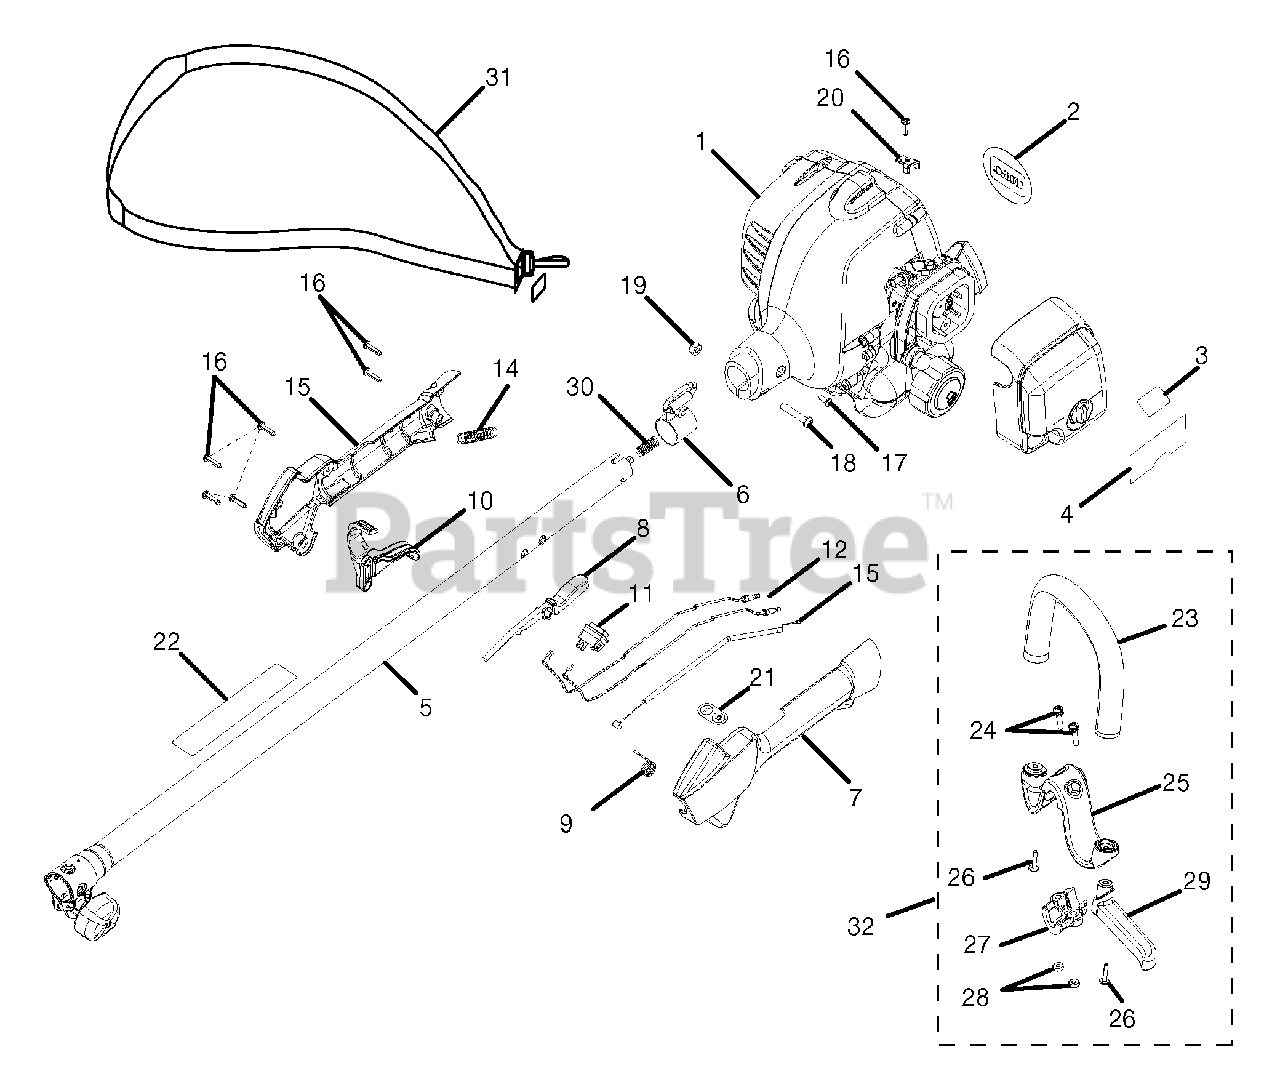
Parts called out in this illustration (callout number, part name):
1	Engine Assembly
2	Logo Label
3	Upper Start Label
4	Lower Start Label
5	Upper Shaft Assembly
6	Hanger Bracket
7	Rear Handle Support
8	Lock-off Button
9	Trigger Spring
11	Switch with Dust Shield
13	Cable, throttle
14	Corrugated Tube
15	Rear Handle Cover
16	Screw (M4 x 1.75 x 16 mm)
17	Screw (#8-16 x 1/2 in.,Tri-Lobular)
18	Screw (M5 x 1 x 30 mm)
19	Hex Nut
20	Retaining Ring
21	On/Off Label
22	Warning Label
23	Assist Handle w/grip
24	12-24 x 1 SEMS
25	M Clamp
26	Slotted Torx Screw
28	12 - 24 Hex nut
29	Barrier Bar
30	Spring, Shaft
31	Harness Assembly W/Label
32	Assist Handle W/Barrier
33	Operator's Manual
